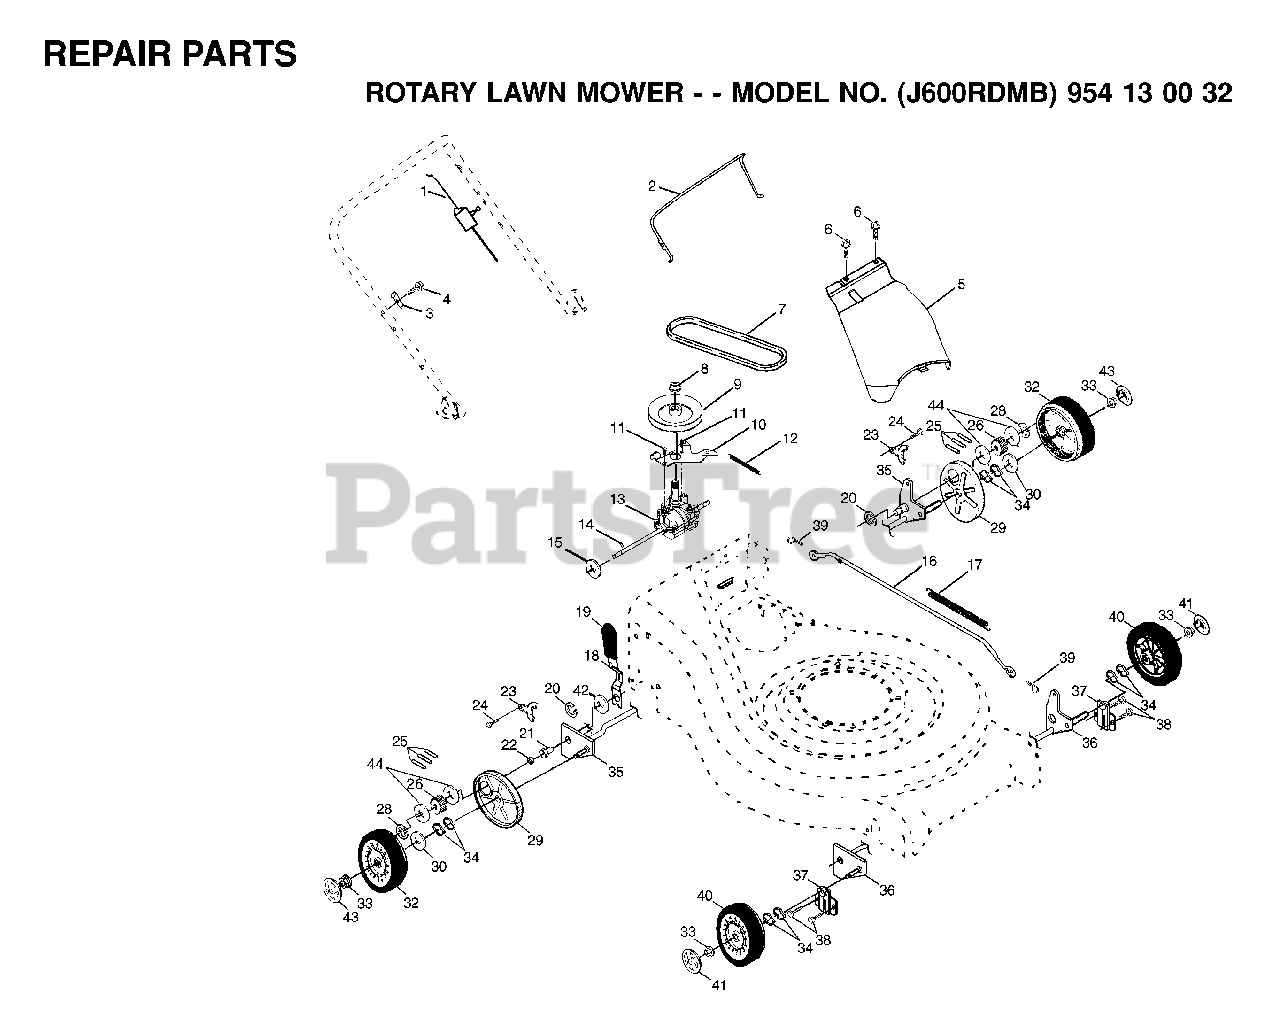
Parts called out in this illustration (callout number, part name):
1	CABLE DRIVE
2	BAIL.CONT.DR.21.RWGD.BLACK
3	DOWNSTOP BRACKET
4	SCREW.HEX.HEAD.WASHER.10-16
5	DRIVE COVER
8	FLANGED LOCKNUT 3/8-16 ZINC
13	TRANSMISSION ASM. (WALK)
14	PIN.SPRING.THRUST
15	THRUST WASHER
16	ROD
17	SPRING
18	SPRING
19	KNOB
21	RP BEARING SUPPORT
23	BRACKET
25	REPL BY 532 1700-11
26	DRIVE PINION
28	E-RING 7/16 RE
29	DUST SHROUD PM
30	WASHER FLUT
33	HEX FLANGE LOCKNT
34	WAVE WASHER
35	SHAFT ASSY
36	SHAFT ASSY
37	RETAINER.FRONT.SHAFT
39	RETAINER CLIP
40	WHEEL ASMBLY FRONT
41	CAP.HUB.ARC.SPOKE.8".LP
44	WASHER
